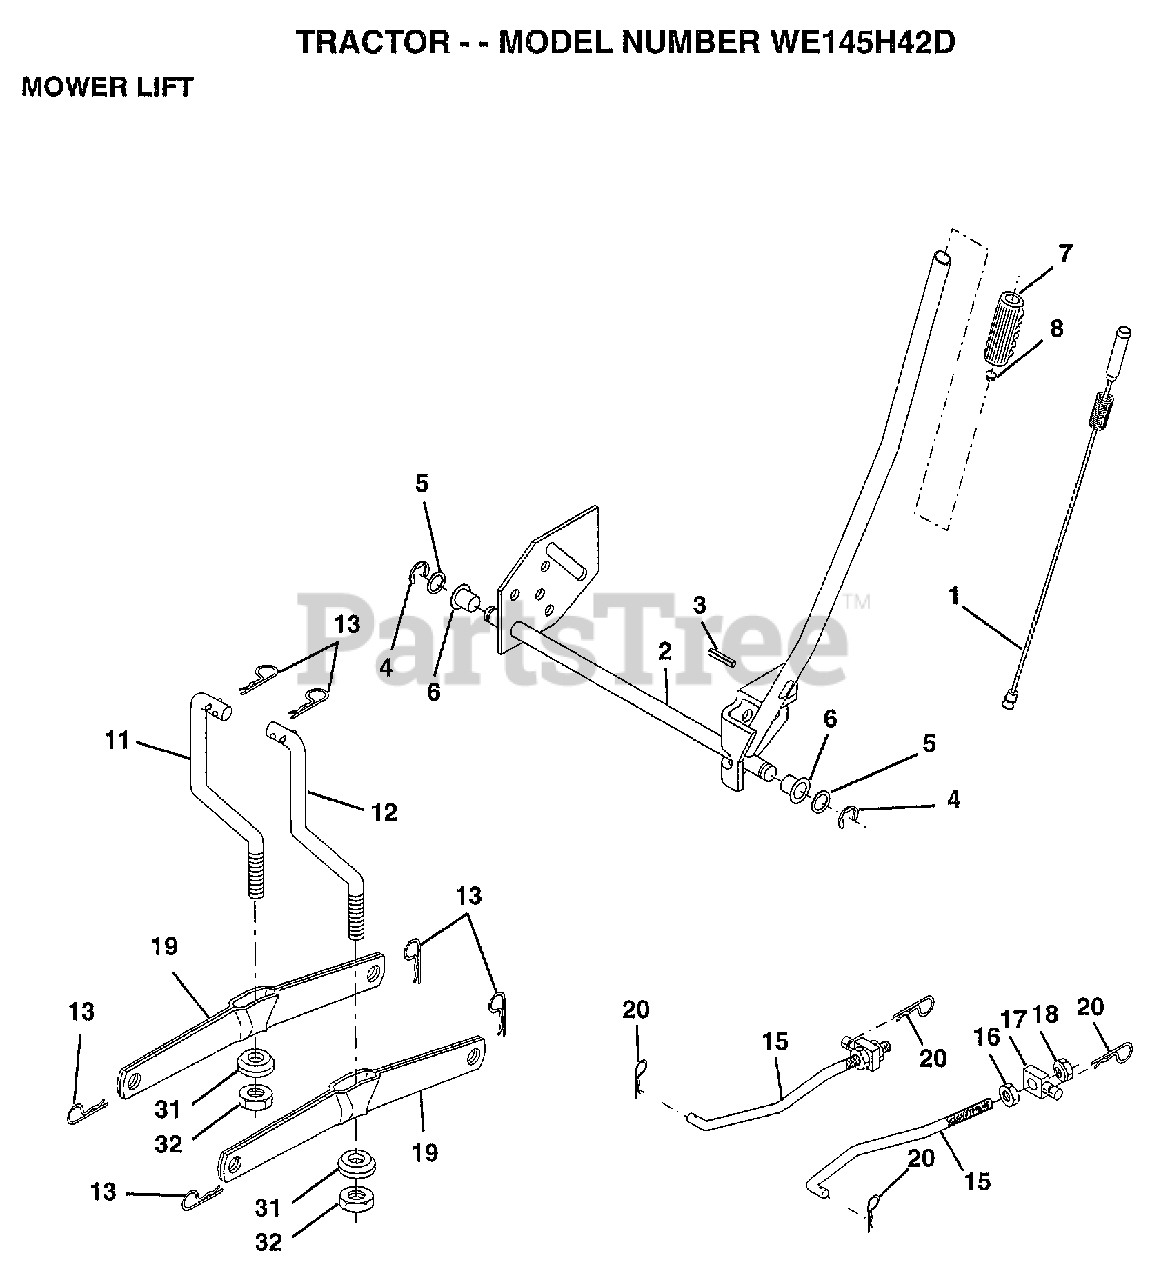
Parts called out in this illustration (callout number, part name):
1	WIRE ASM W.SPRING
2	"SHAFT ASM LIFT,RH"
3	PIN-GROOVE LT
5	WASHER
6	NYLON BEARING
7	GRIP
15	LINK.FRONT
16	NUT
17	TRUNION
18	NUT LTV
19	ARM SUSP REAR
20	RETAINER SPRING
31	BEARING PVT LH
32	NUT.CROWNLOCK.3/8
